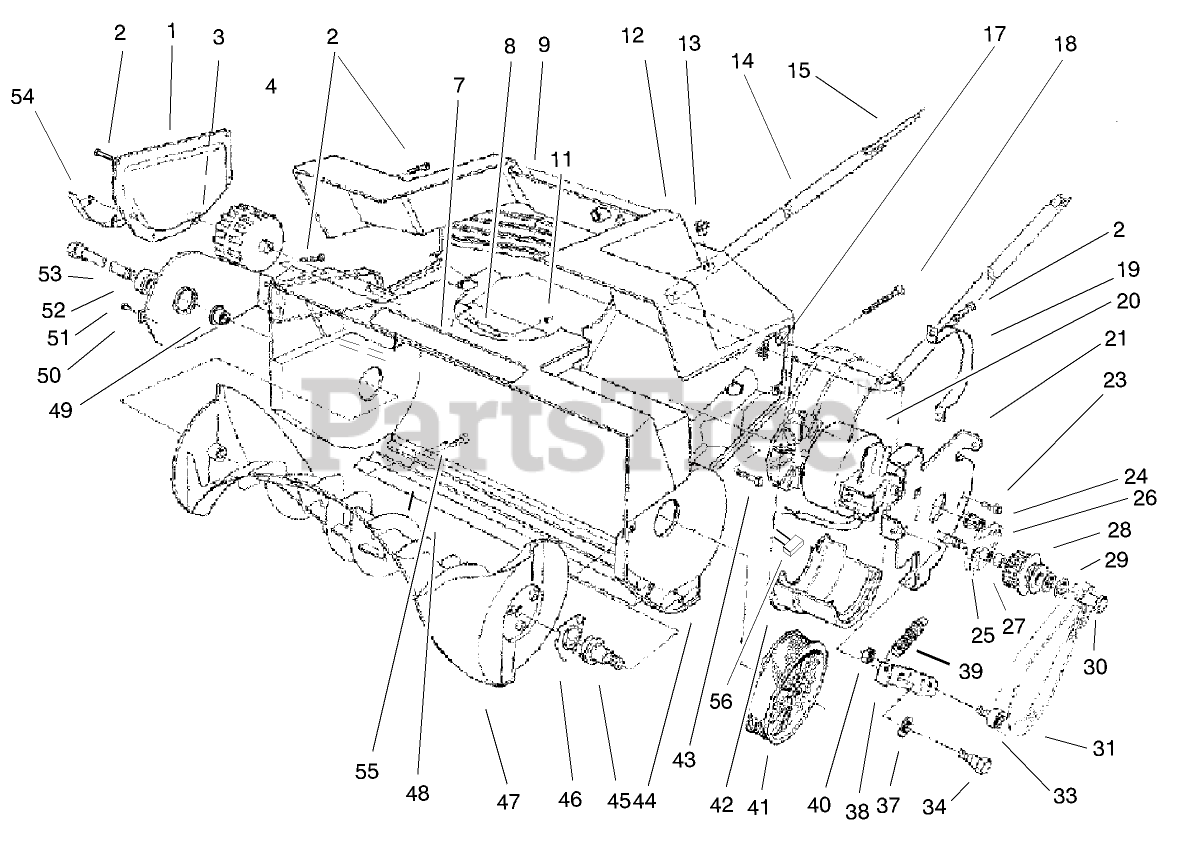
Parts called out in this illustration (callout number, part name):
1	PLATE - SIDE
2	SCREW-PPH
3	PUSHNUT-CAP, WASHER
4	WHEEL, 1200/1800
7	AXLE SHAFT
8	STRAIN RELIEF-GRIPMASTR
9	DECAL-DANGER
11	CONNECTOR SCREW
12	SHROUD-1800 PC (SERVICE)
13	BUSHING
14	TUBE-LOWER, 1800
17	FOAM FILTER
18	SCREW-PLASTIC, PPH
19	STRAP-MOTOR, FINISHED
20	MOTOR-230V 1800
21	PLATE - MOTOR ASSY.
23	TEKS SCREW
24	DRIVER PULLEY
25	BELT-PULLEY, IDLER/DRIVER
26	WASHER
27	Loose Parts Package
29	WASHER-THRUST
30	IDLER BOLT
33	IDLER BEARING
34	SCREW-SHOULDER
37	WASHER
38	IDLER BRACKET
39	IDLER SPRING
40	NUT-LOCK, NI
41	DRIVEN PULLEY
42	1800 CLAMP MTR BRCKT
43	SCREW-HWH THD CUT
44	ROTOR/HOUSING 1800
45	SHAFT, ROTOR DRIVE
46	COUPLER, ROTOR
47	ROTOR - 1800 SNOWBLOWER
48	SCRAPER - 1800
49	BUSHING
51	RIVET-POP
54	SKID, 1800
55	SCREW-PLASTITE, #6-19 X 1.0
56	FILTER-RFI
